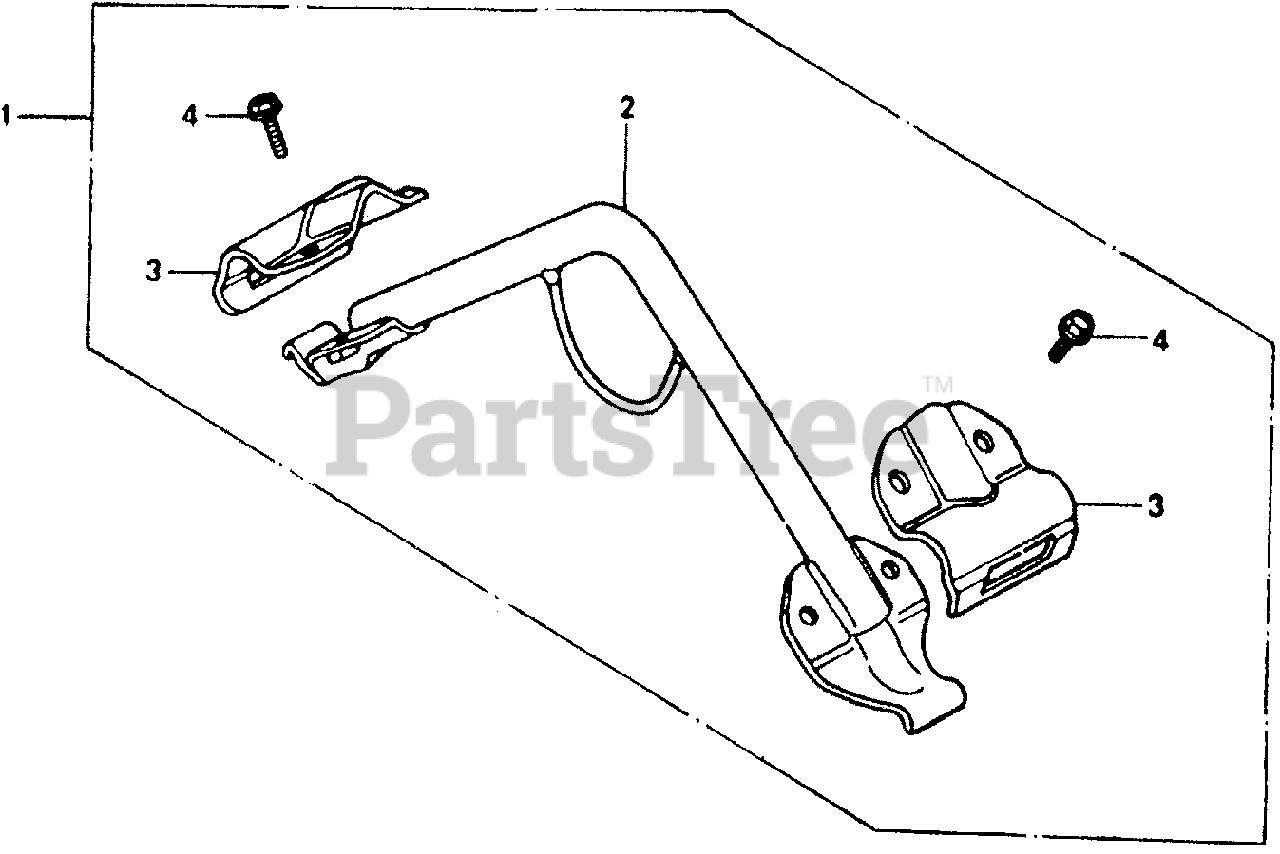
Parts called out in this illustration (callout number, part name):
1	HANGER KIT
2	HANGER
3	BRACKET, HANGER (UPPER)
4	BOLT, FLANGE (8X16)
